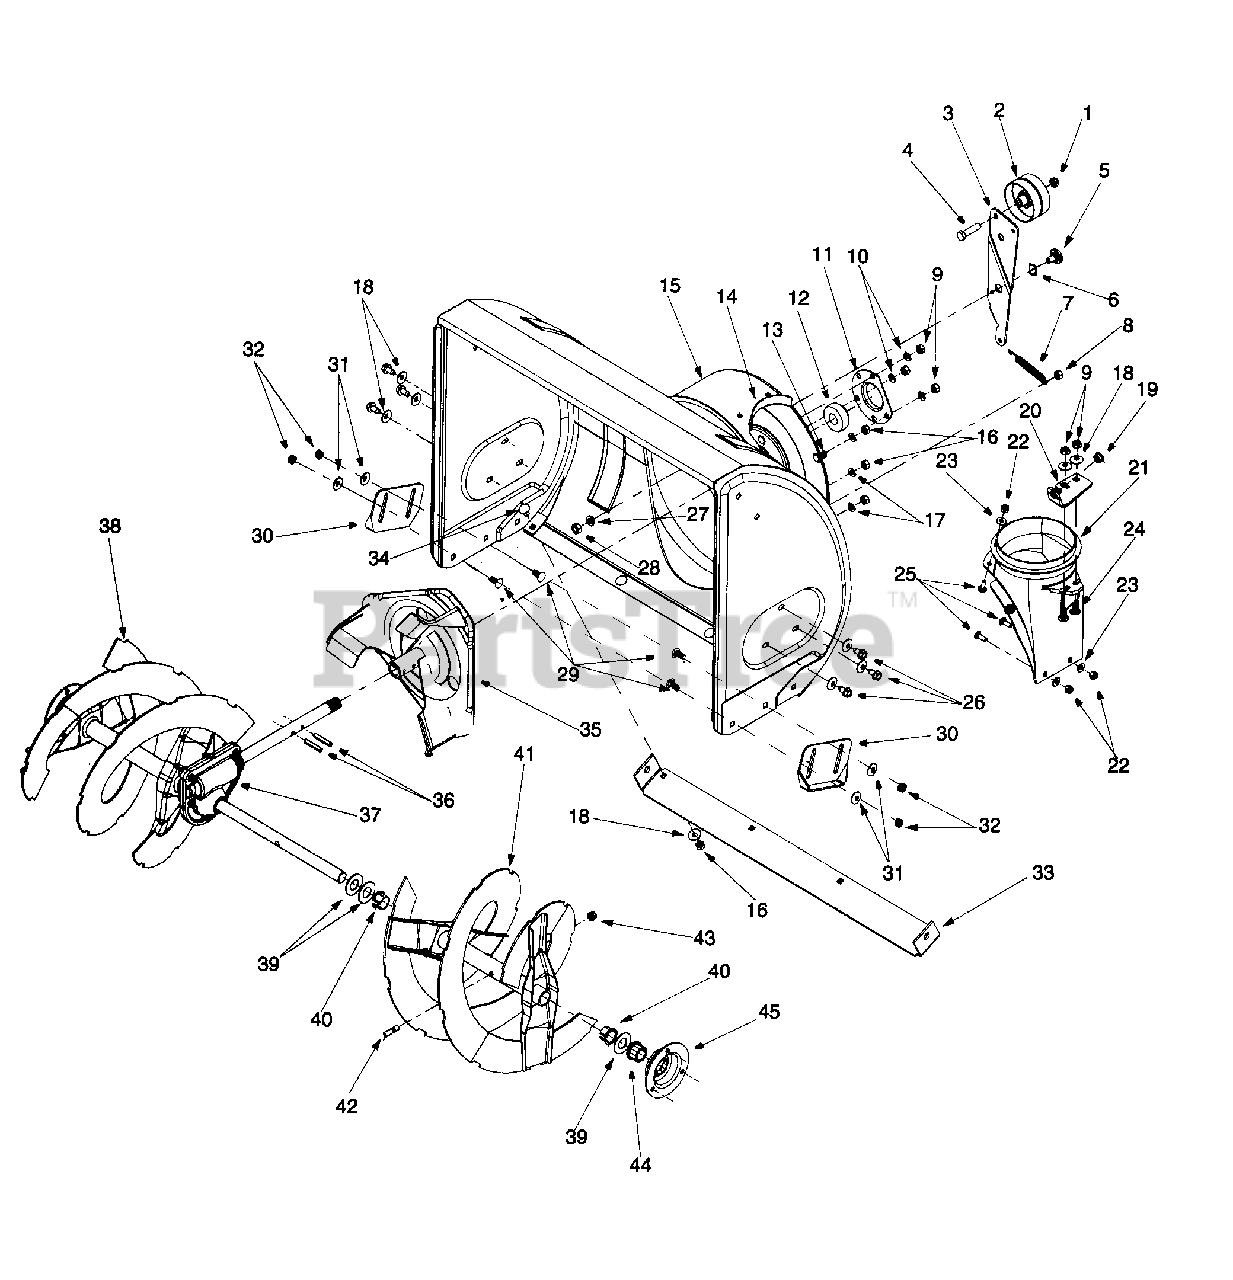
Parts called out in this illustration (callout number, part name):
1	Lock Jam Nut 3/8-24
2	Flat Idler
4	Hex Cap Screw 3/8-24 x 1.50
5	Shoulder Screw
6	Wave Washer
7	Extension Spring
8	Hex Nut 5/16-18
9	Hex Nut 5/16-18
10	Lock Washer 5/16
11	Housing
12	Ball Bearing
13	Carriage Bolt 5/16-18
17	Lock Washer 5/16
18	Bell Washer
19	Bushing
21	Chute Adapter
22	Hex Lock Nut 1/4-20
23	Flat Washer
24	Carriage Bolt
25	Carriage Screw 1/4-20 x .75
26	Hex Washer Screw 5/16-18
27	Lock Washer 3/8
28	Hex Nut 3/8-16
29	Carriage Bolt 5/16-18 x .75
31	Bell Washer
32	Hex Nut 5/16-18
34	Carriage Bolt 5/16-18 x .62
37	24" Gear Assembly
40	Flange Bushing
42	Shear Bolt 5/16-18 x 1.5
43	Lock Nut 5/16-18
44	Hex Flange Bearing
